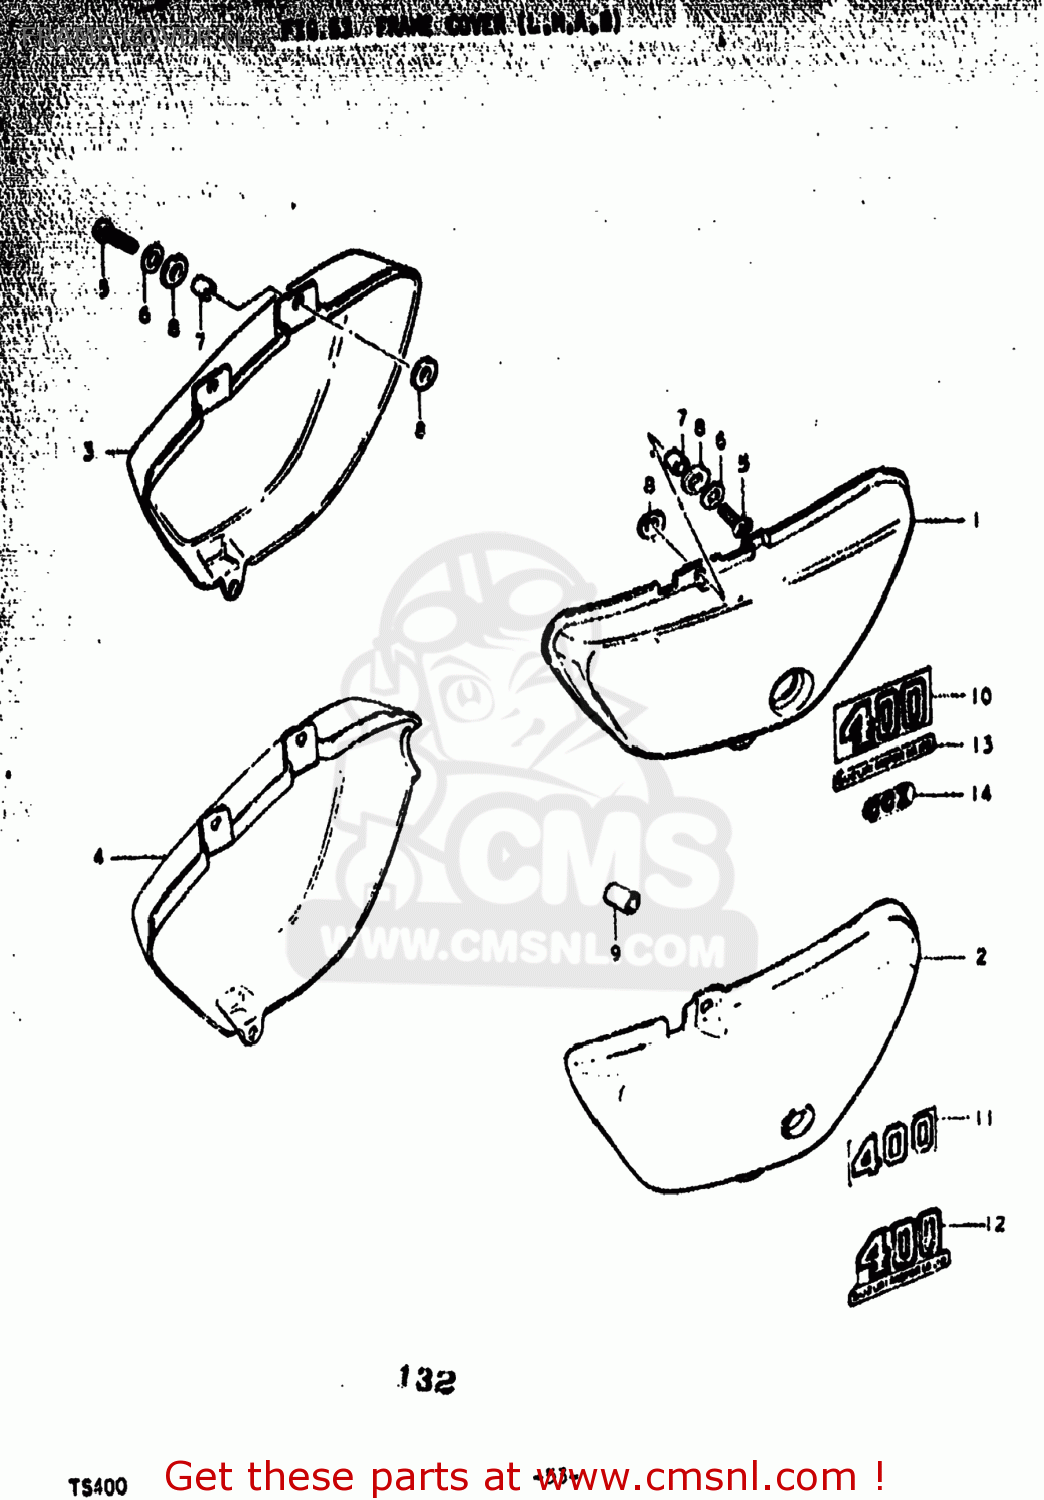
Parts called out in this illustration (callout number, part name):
1	COVER,FRAME,LEFT
2	COVER,FRAME,LEFT
3	COVER,FRAME,RIGHT
4	COVER,FRAME,RIGHT
5	SCREW
6	WASHER
7	SPACER (6.1X8X9.5)
8	CUSHION
9	CUSHION
10	EMBLEM
11	EMBLEM
12	EMBLEM
13	LABEL,COMPANY NAME
14	EMBLEM,CCIS
